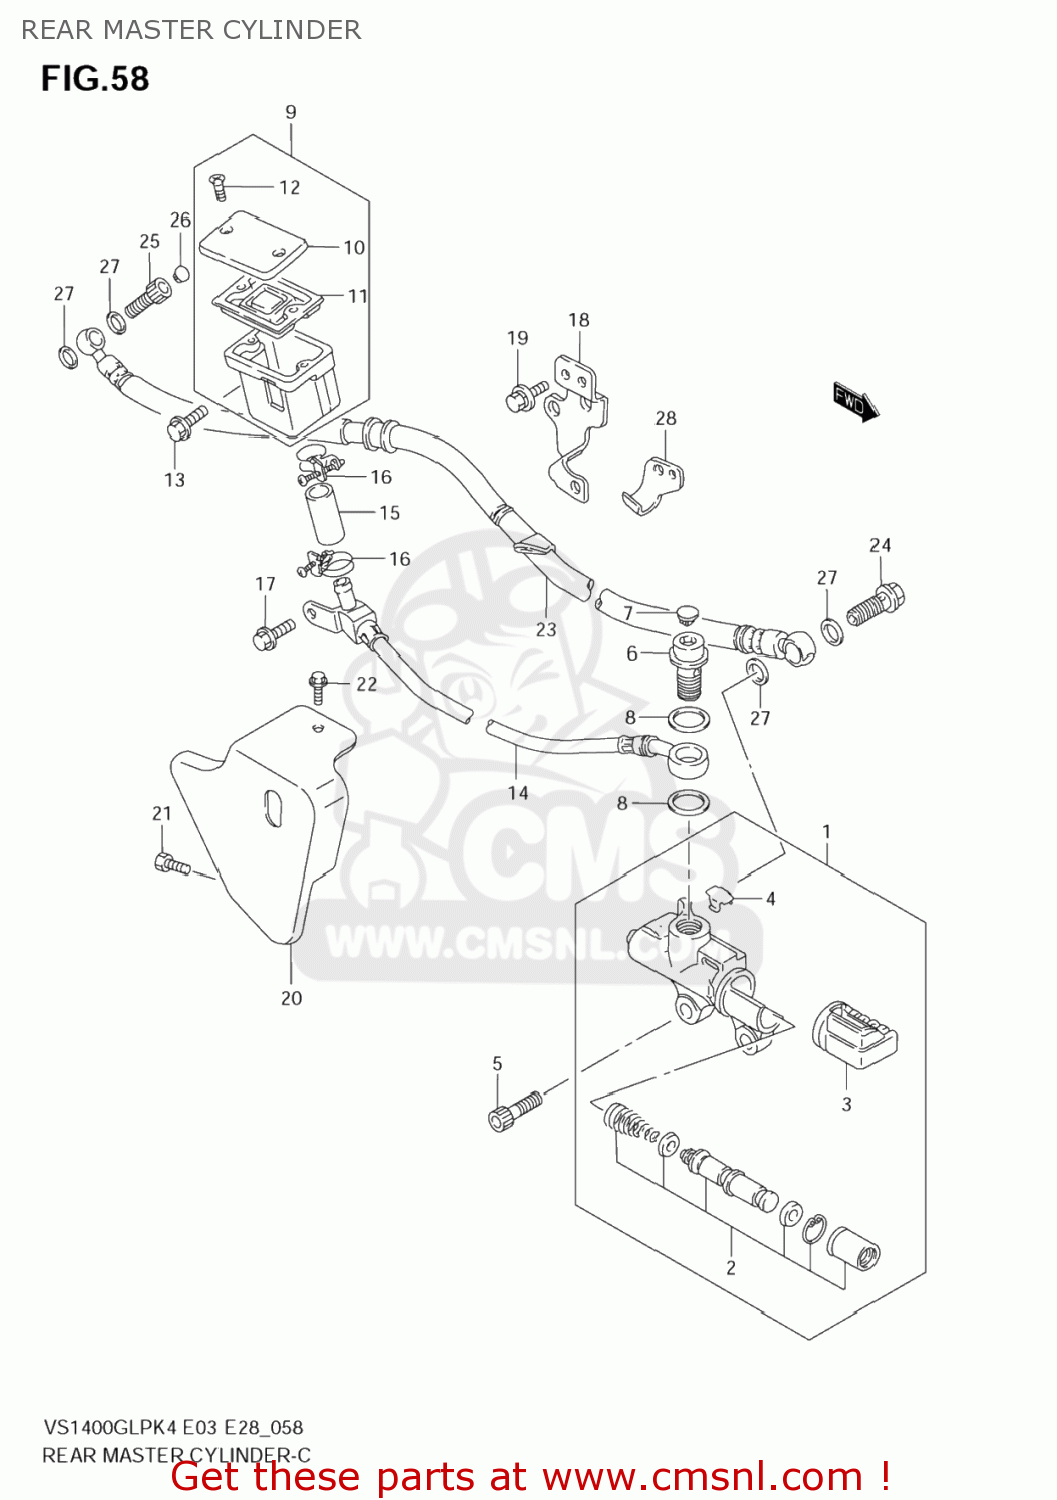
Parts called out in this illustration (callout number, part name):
1	CYLINDER ASSY,RR MASTER
2	PISTON/CUP SET
3	BOOT
4	PLATE,STOP
5	BOLT(8X30)
6	BOLT UNION
7	CAP(OD:12)
8	WASHER,BRAKE FLUID
9	TANK ASSY,RESERVOIR
10	CAP
11	DIAPHRAGM
12	SCREW
13	BOLT
14	HOSE,RESERVOIR TANK
15	HOSE,RESERVOIR TANK
16	CLIP
17	BOLT
18	BRACKET,RESERVOIR TANK
19	BOLT
20	COVER,RESERVOIR TANK
21	SCREW(6X10)
22	BOLT
23	HOSE,REAR BRAKE
24	BOLT UNION
25	BOLT UNION
26	CAP(OD:12)
27	WASHER(10X15X1.5)
28	CLAMP,RR BRAKE HOSE
